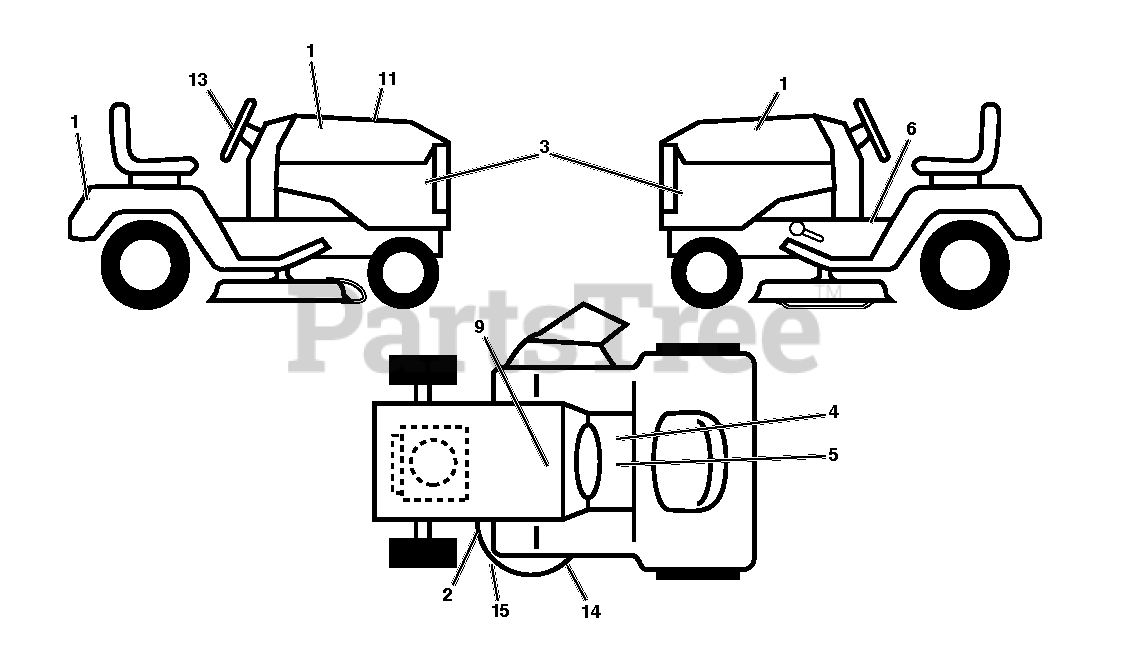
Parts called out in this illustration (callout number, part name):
2	DECAL
5	DECAL, WARNING SPARK ARRESTOR
9	DECAL BTRY SYMBOLS
11	DECAL.RPL
14	DECAL.MOWER.SCH.48/54
15	DECAL.MOWER
